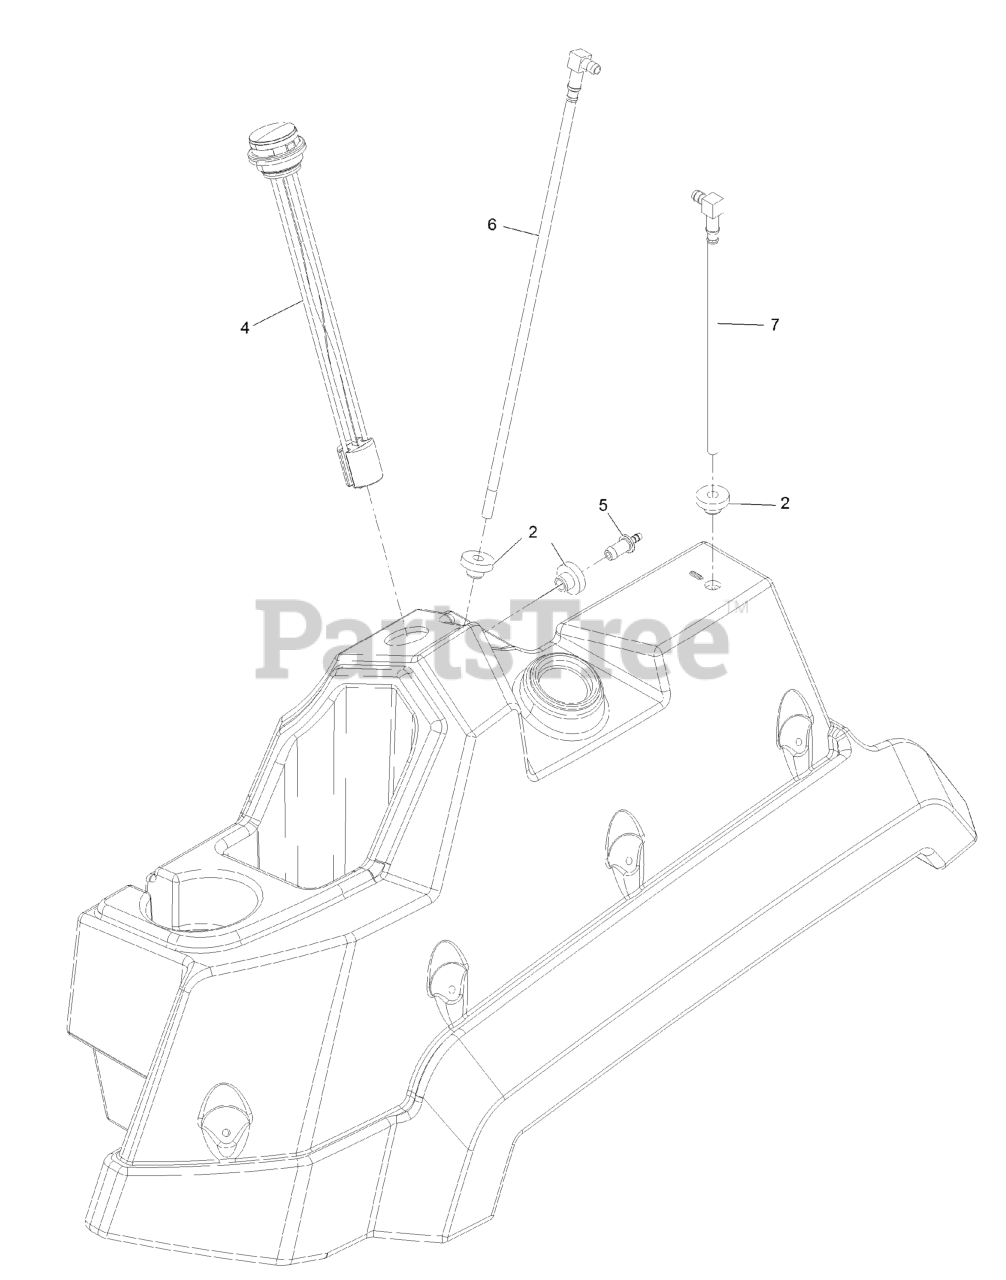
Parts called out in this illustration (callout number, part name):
2	BUSHING
4	GAUGE-FUEL
5	FITTING-ORIFICE, STRAIGHT
6	PICK-UP-FUEL
7	RETURN-FUEL
